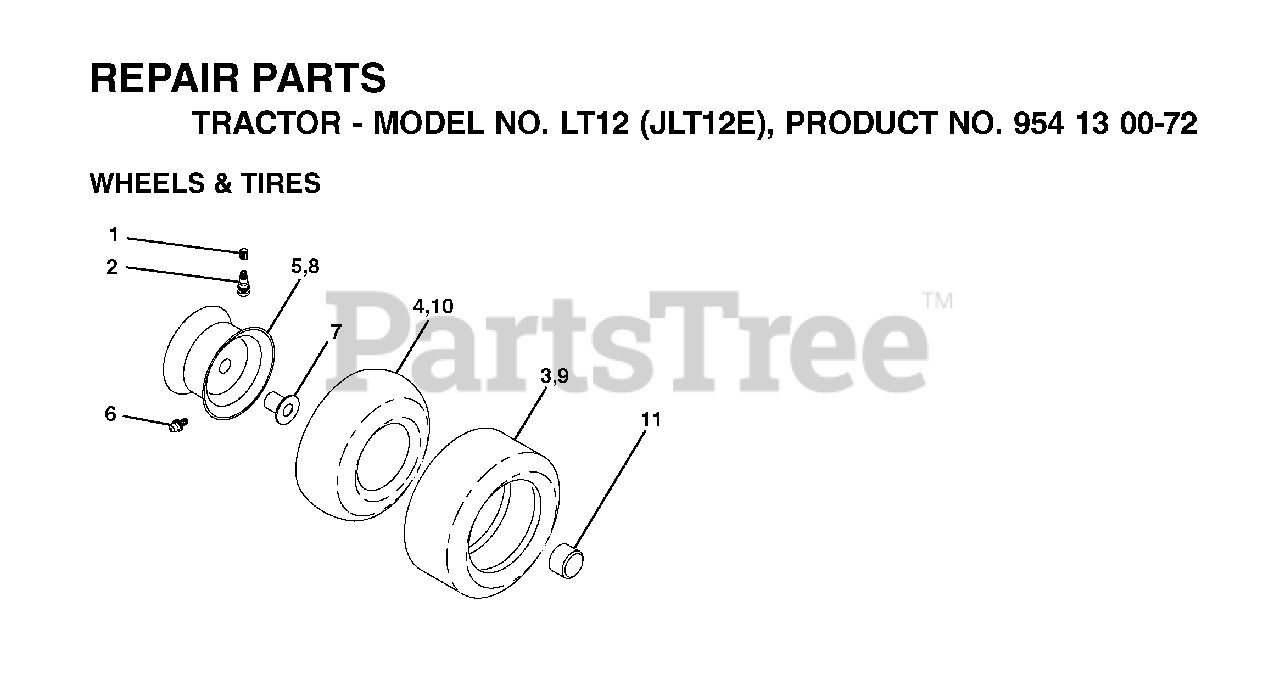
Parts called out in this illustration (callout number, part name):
1	VALVE CAP
2	VALVE STEM LT
3	TIRE HEAVY DUTY
4	TUBE.5.3/4.5/6
5	RIM ASM 6" FRONT SILVER
6	FITTING LT
7	BEARING T
8	RIM ASM 8" REAR SILVER
9	TIRE
10	TUBE
11	CAP, AXLE BLK
